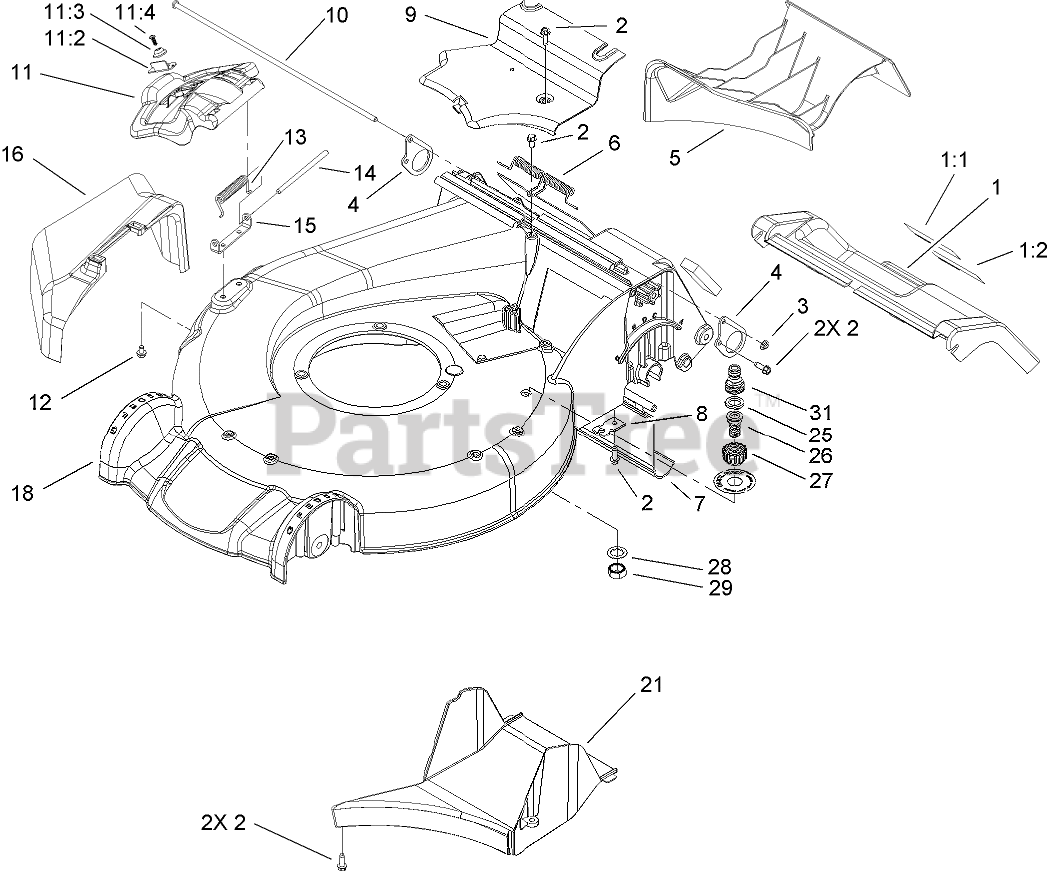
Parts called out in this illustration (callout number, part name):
1	DOOR-SERVICE
1:1	DECAL-WARNING
1:2	DECAL-WARNING
2	SCREW-HWHTF
3	NUT-SPEED
4	PLATE-SUPPORT, DOOR
5	MULCH PLUG ASM
6	Spring-Door, Rear
7	SHIELD-TRAILING
8	BRACKET-CABLE, TRACTION
9	COVER-BELT
10	ROD-SUPPORT, DOOR
11	DISCHARGE DOOR ASM
11:2	LATCH-DOOR
11:3	CAP-DOOR
11:4	SCREW-PLASTITE
12	SCREW-HWH
13	SPRING-TORSION
14	ROD-COVER
15	BRACKET-COVER
16	CHUTE-DISCHARGE, SIDE
18	HOUSING ASM
21	TUNNEL-DISCHARGE
25	WASHER-SEAL, WASHOUT PORT
26	PORT-WASHOUT
27	COUPLING-HOSE, WASHOUT PORT
28	WASHER-TOOTH, INTERNAL
29	NUT-JAM
31	ADAPTER-CONNECT, QUICK
